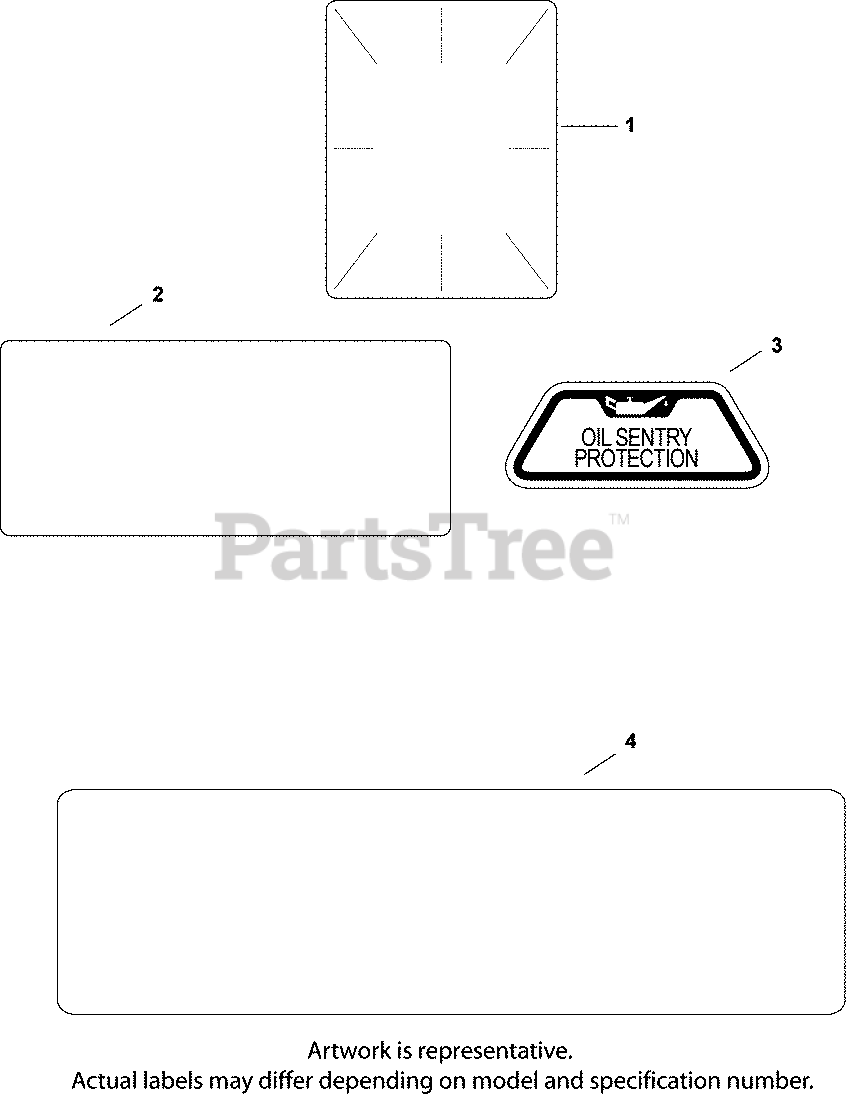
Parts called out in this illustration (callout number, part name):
1	DECAL, CLEAR LAMINATE USE 25 113 70-S
2	DECAL, REPL ENGINE(NONCERT)
3	DECAL, OIL SENTRY - (#DSC)
4	DECAL, 25 HP - DISCONTINUED
